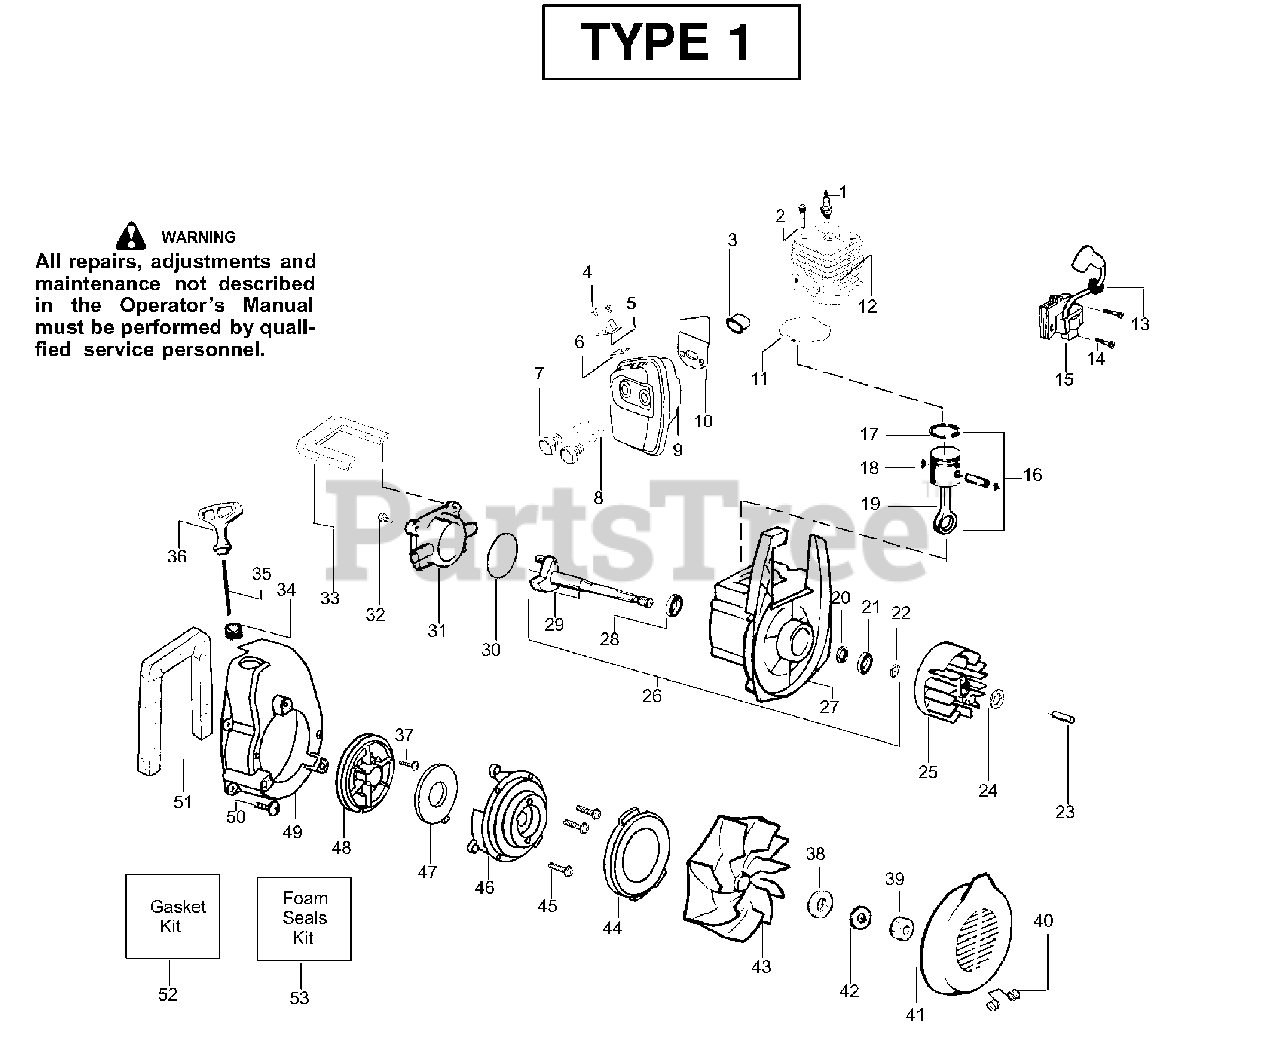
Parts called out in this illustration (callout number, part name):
1	Spark Plug (RCJ-6Y)
3	Insulator-Heat
5	Deflector-Muffler
6	Kit-Spark Screen
7	Bolt-Muffler-external
8	Screw-Muffler-Internal
9	Kit-Muffler
10	Gasket-Baffle (kit)
11	Gasket-Cylinder (kit)
12	Kit-Cylinder
13	Grommet-Ign. Module
14	Screw-Ignition Module
15	Ignition Module
16	Kit-Piston
17	Piston Ring
18	Retainer-Piston Pin
19	Assy-Connecting Rod
20	Seal-Crankcase
21	Bearing-Outer
22	Retainer Ring-C'chaft
23	Spacer-Flywheel
25	Assy-Flywheel
26	Assy-Crankcase/Crankshaft
27	Assy-Crankcase
28	Bearing-Inner
29	Assy-Crankshaft
30	O-ring-C/case (kit)
31	Cover-Crankcase
32	Screw
33	Foam-219mm (kit)
34	Eyelet-Flange
35	Kit-Rope
36	Handle-Starter
37	Screw-Rope
38	Washer-Flat
40	Spring-Return Cover
41	Inlet Door
42	Washer-Belleville
43	Assy-Impeller
44	Seal-Ring
46	Housing-Pulley
47	Spring-Starter
48	Kit-Starter Pulley
49	Fan Housing
50	Screw
51	Foam-365mm (kit)
52	Kit-Gasket
53	Kit-Foam Seals
